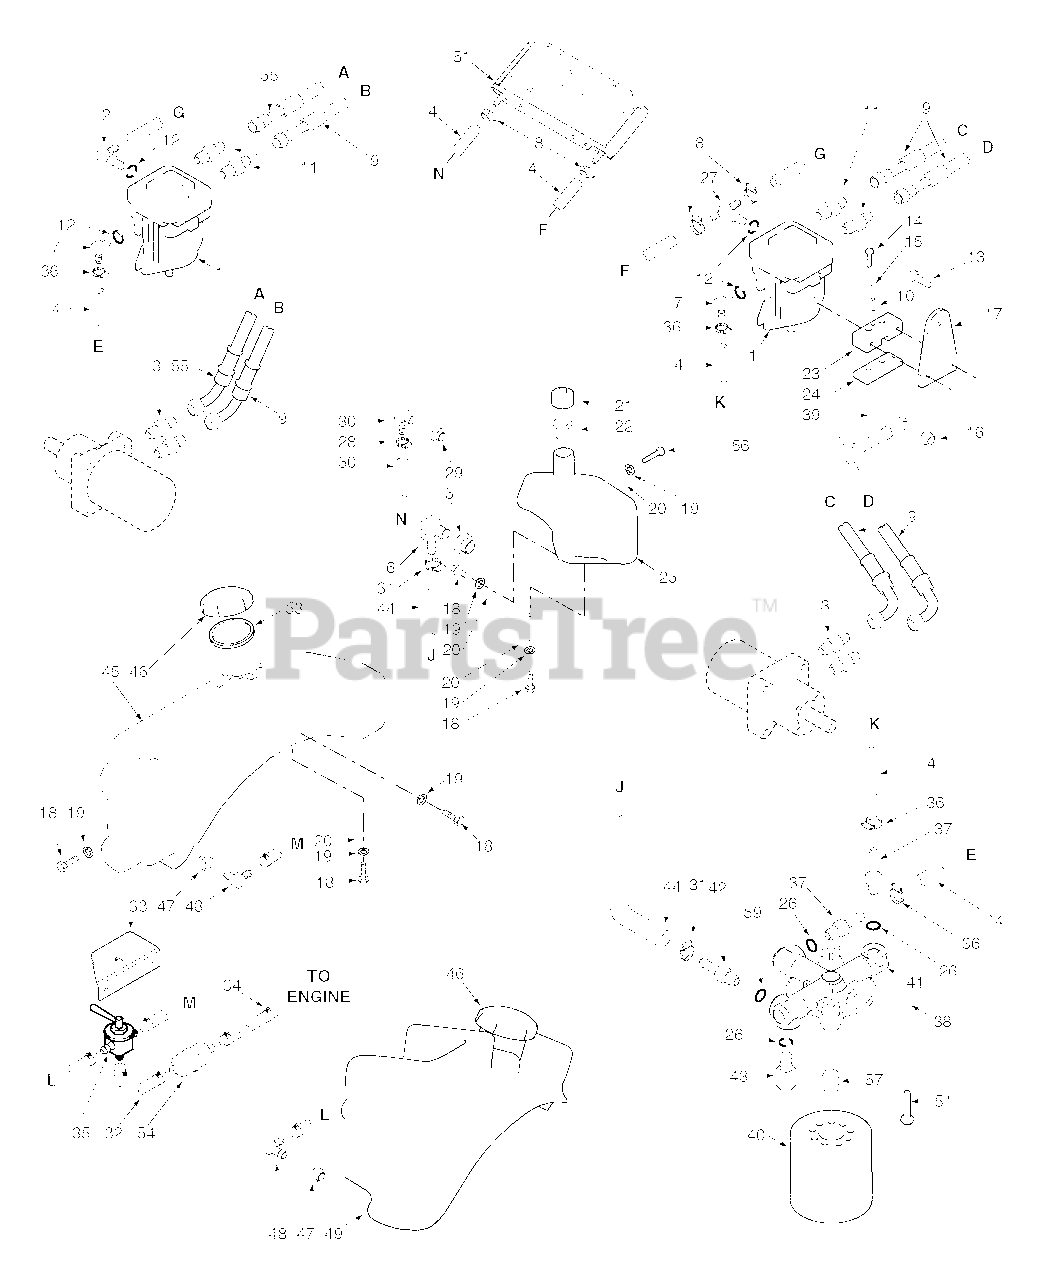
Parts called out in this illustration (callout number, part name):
1	Pump, BDP-10A-316 (L.H.)
2	Elbow, 90 Degree 9/16 O-Ring x 3/8 Hose
3	Fitting, 1/2" JIC x 5/8 O-Ring
4	Hose, 3/8 Pushlock (Specify length)
5	Bushing
6	Fitting
7	Elbow, 90 Degree 9/16 O-Ring x 3/8 Hose
8	Hose Clamp, .69 Dia.
9	Hose Assembly
10	Roll Pin
11	Fitting, 1/2" JIC x 1/2" O-Ring
12	O-Ring
13	Bolt, Hex Head 3/8-16 x 1-1/2"
14	Bolt, Hex Head 1/4-20 x 1-1/4"
15	Lockwasher
16	Nut, Elastic Stop 3/8-16
17	Control Lever
18	Bolt, Hex Head 5/16-18 x 3/4"
19	Lockwasher, 5/16
20	Flatwasher, 5/16-.375 x .875 x .083
21	Cap, Hydraulic Tank
22	Insert, Filler Neck
23	Control Block
24	Clamp Plate
25	Hydraulic Tank Assembly w/fittings
26	O-Ring
27	Tee Fitting, O-Ring to Barb
28	Clamp, .69 Max. / .25 Min. Dia.
29	Bushing
30	Elbow, 0.38 Hose
32	Fuel Hose, 1/4 ID
33	Bracket Fuel Valve
34	Clamp, Fuel Hose 1/4 Hose ID
35	Valve, Fuel Shutoff
36	Clamp, .69 Max. / .25 Min. Dia.
37	Fitting, 9/16 O-Ring x 3/8 Hose
38	Nut, Serr. Flange 5/16-18
39	Flatwasher, 3/8-.391 x .938 x .105
40	Oil Filter
41	Filter Head Assembly
42	Fitting, 3/4 O-Ring x 3/8 Hose
43	Plug, 9/16-18 O-Ring
44	Hose, Filter Inlet
45	Fuel Tank RH
46	Cap, Fuel Tank
47	Tank Bushing
48	Elbow, 90 Degree
49	Fuel Tank LH
50	Hose, 3/8 Pushlock 15" Long
51	Cooler, Transmission
52	Screw, 1/4-20 x 2"
53	Gasket, Gas Tank Cap
54	Fuel Filter
55	Hose Assembly
56	Bolt, Hec Head 5/16-18 x 1-1/2
57	Nipple, Oil Filter 1.0-12 UNF-2A x 1-1/4"
58	Bolt, Hex Head 5/16-18 x 2"
59	O-Ring, 3/4"
